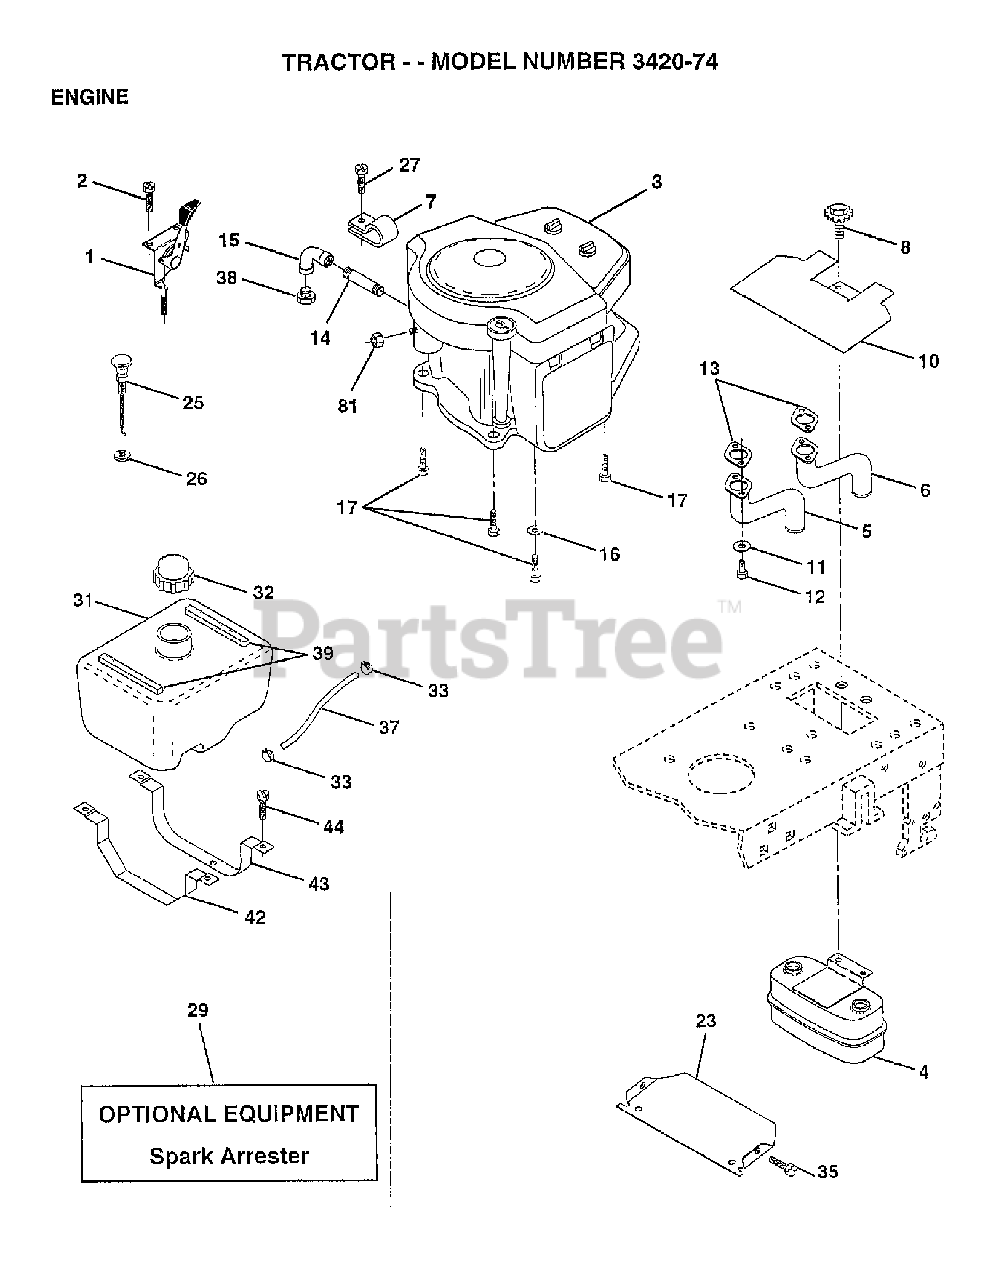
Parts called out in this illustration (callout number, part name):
1	DECK W/DECALS 72" HUS
3	Poulan TBD
4	MUFFLER.TWIN.CYL.LOW.TONE
5	EXHAUST ASM. LEFT
6	EXHAUST ASM. RIGHT
10	SHIELD HEAT LT
11	LOCKWASHER
13	GASKET (B&S 692282)
14	NIPPLE, PIPE 3/8NPT X 4-1/2
15	ELBOW
16	LOCKWASHER
25	CONTROL.CHOKE.51.00.BLK.W/BEND
26	NUT KEPS 3/8 - 24 UNF
27	SCREW.TT.#10-32X.5.3/8.FLANGE
29	KIT.SPARK ARRESTOR(392390 B&S)
33	HOSE CLAMP
35	Screw, Lt
37	LINE FUEL 7.5"
